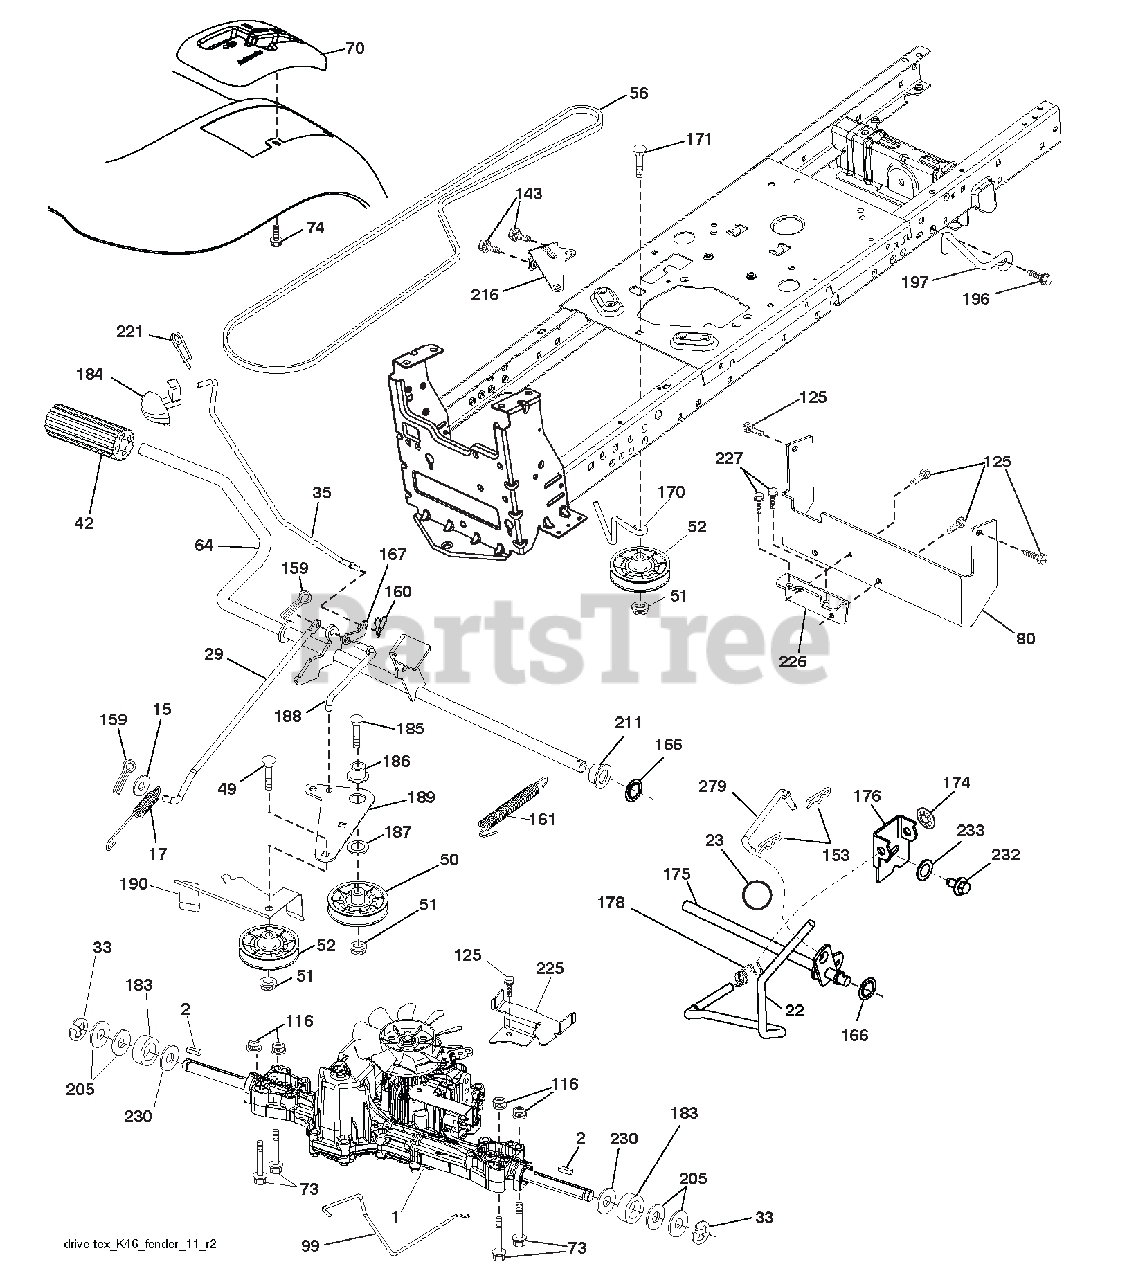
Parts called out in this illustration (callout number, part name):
1	Engine Kohl Model No. SV715-3035 (581497501) (Order Parts from Engine Manufacturer)
2	KEY.SQUARE.2.0 X .1845/.1865
15	WASHER.13/32 X 13/16 X 16 GA.
17	SPRING.BRAKE.K46.GREEN
22	ROD.SHIFT.FENDER.TLT.2006
23	KNOB DELUXE
29	ROD.BRAKE.K46
33	E-RING.#5133-75
35	ROD.BRAKE.PARKING.LT.TEX
42	COVER PEDAL BLK ROUND
49	BOLT.RDHD.3/8-16UNCX1-3/4.GR5
50	IDLER.FLAT.910"OFFSET
51	Nut, Hex, Flangelock 3/8-16
52	IDLER.V-GROOVE.910"OFFSET
56	V-BELT.MOWER.92.40.42/K46
64	SHAFT ASM.PEDAL.BRAKE CONTROL
70	CONSOLE.SHIFT STL.HYD.BLACK.TX
73	BOLT 5/16-18 X 2 1/2 G.5
74	SCREW.HEX.WSH.HI-LO.1/4X1/2UNC
80	STRAP.TORQUE.K46/18"TEX
99	ROD.SPRING.BYPASS.K46.LT.Z
116	Nut, Lock Hex Flange 5/16-18 u
125	SCREW.5/16-18X3/4.SMGML.TAP/BL
143	SCREW.THDROL.5/16-18 X 1/2TYTT
153	RETAINER SPRING
159	PIN.COTTER.1/8 X 3/4.CAD.
160	RETAINER.CLIP(M).DIA.290
161	SPRING.RETURN.CLUTCH.6.75
166	NUT PUSH .625
167	LATCH.BRAKE.PARKING
170	KEEPER BELT CENTERSPAN
171	BOLT.RD.HD.SQ.NK.3/8-16UNC X 2
174	NUT.PUSH..500
175	SHAFT ARM SHIFT
176	ARM.CLEVIS.ROD.SHIFT
178	SPRING.SHIFT.GT.2006
183	SPACER.AXLE.HYDRO/PEERLES
184	HANDLE.PARKNG.BRAKE.LT.TEX.667
185	BOLT.RDHD.3/8-16UNC X2-3/4 GR5
186	SPACER.RETAINER
187	WASHER.13/32 X 2 X 10 GA.
188	LINK.CLUTCH.GROUND DRIVE
189	BELLCRANK.GROUNDRIVE.NSTG/NSTL
190	KEEPER.BELLCRANK.DRIVE.GROUND
196	SCREW.3/8-16X1.SMGML.TAP/R.BLK
197	LINK CLUTCH ANTI-ROTATION
205	WASHER.25/32 X 1-5/8 X 16GA.
211	BUSHING.SHAFT.BRAKE.HAND CONTR
216	BRACKET.PULLEY.IDLER.WTEX
221	RETAINER.SPRING.CLIP.HANDLE
225	KEEPER.BELT.TRANSAXLE.K46
226	BRACKET.MOUNT.TORQUE.K46.TLT
227	SCREW 5/16-18 X 3/4
230	WASHER.HARDEN..793 X 1.637X060
232	BOLT.FIN HEX.7/16-14X1 GR5
233	WASHER.SERRATED
279	LINK SHIFT T/A
